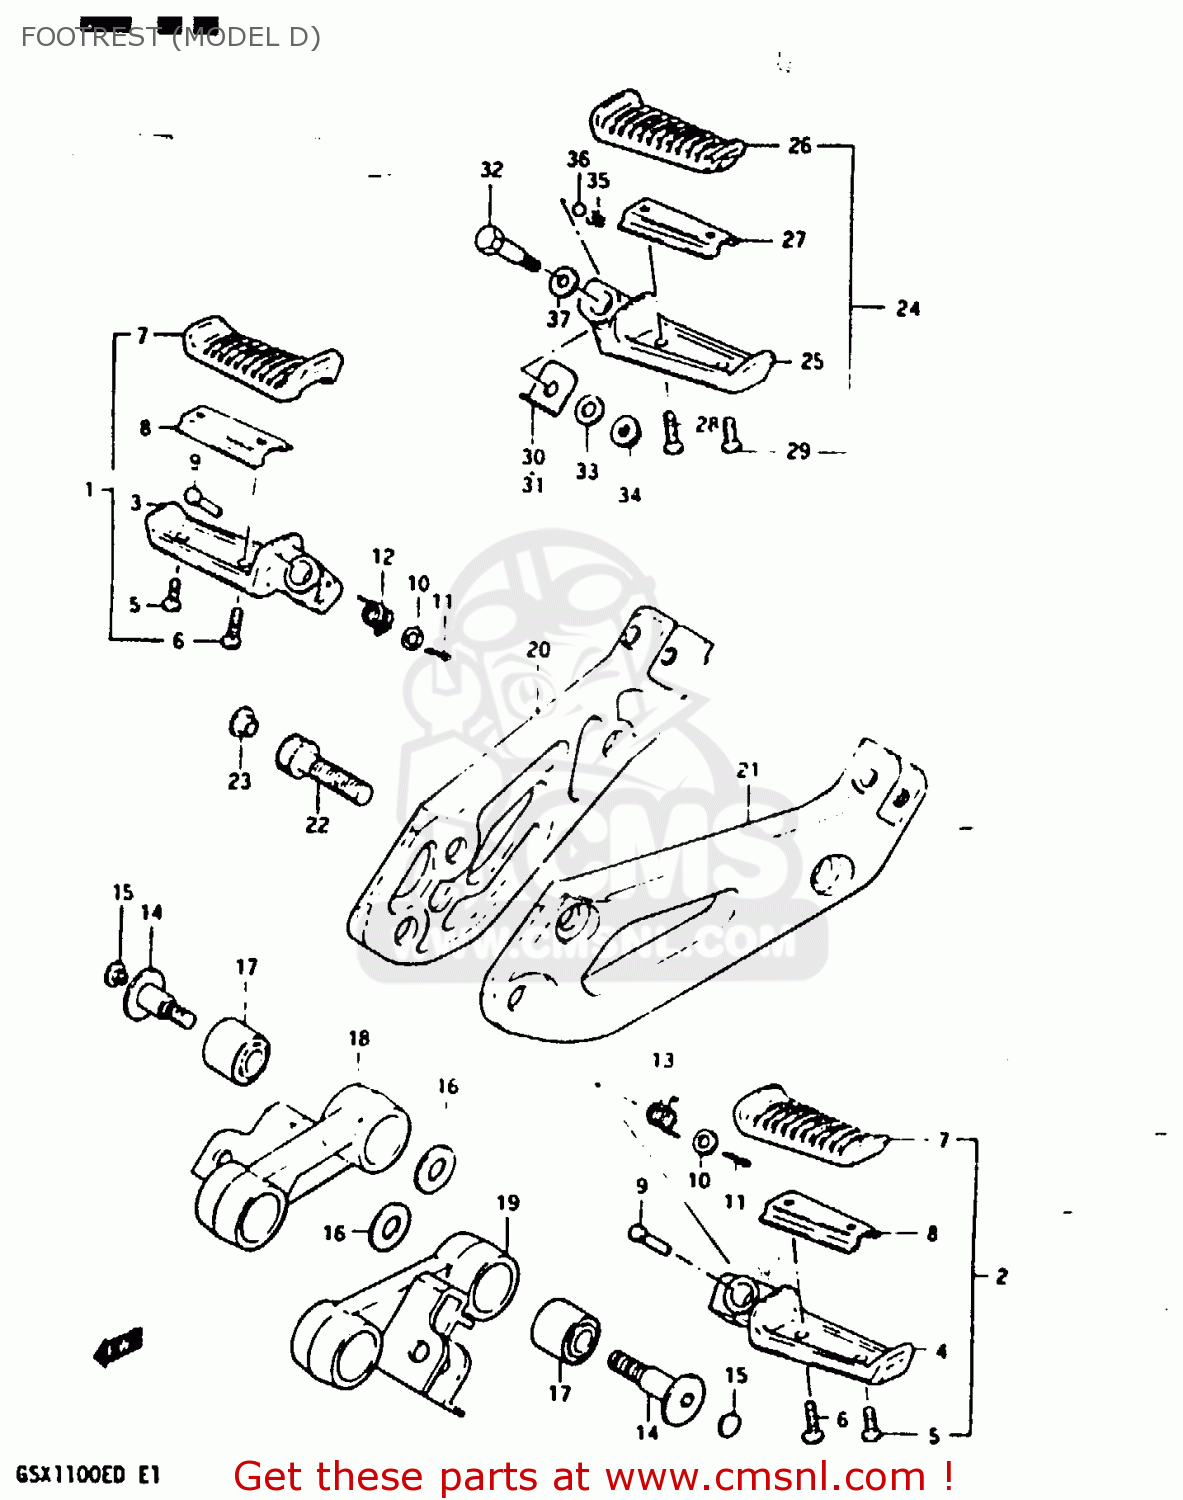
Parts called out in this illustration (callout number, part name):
1	FOOTREST ASSEMBLY,FRONT,RIGHT
2	FOOTREST ASSEMBLY,FRONT,LEFT
3	BAR,FRONT FOOTREST
4	BAR,FRONT FOOTREST,LEFT
5	SCREW
6	SCREW
7	RUBBER,FR FOOTREST
8	PLATE,FRONT FOOTREST RUBBER
9	PIN
10	WASHER
11	PIN 20X20
12	SPRING
13	SPRING
14	BOLT(10X50)
15	CAP
16	WASHER
17	BUSH
18	HOLDER,FRONT FOOTREST,RIGHT
19	HOLDER,FRONT FOOTREST,LEFT
20	BRACKET,MUFFLER,RIGHT
21	BRACKET,MUFFLER,LEFT
22	BOLT
23	CAP
24	FOOTREST ASSY,PILLION,R
25	BAR,PILLION FOOTREST,LEFT
26	RUBBER,PILLION FOOTREST
27	PLATE,RUBBER STOP
28	SCREW 5X12
29	SCREW
30	PLATE,PILLION FOOTREST SPRG,R
31	PLATE,SPRING STOP,LEFT
32	BOLT
33	WASHER
34	NUT
35	SPRING
36	BALL
37	SHIM(8.2X22X0.2)
